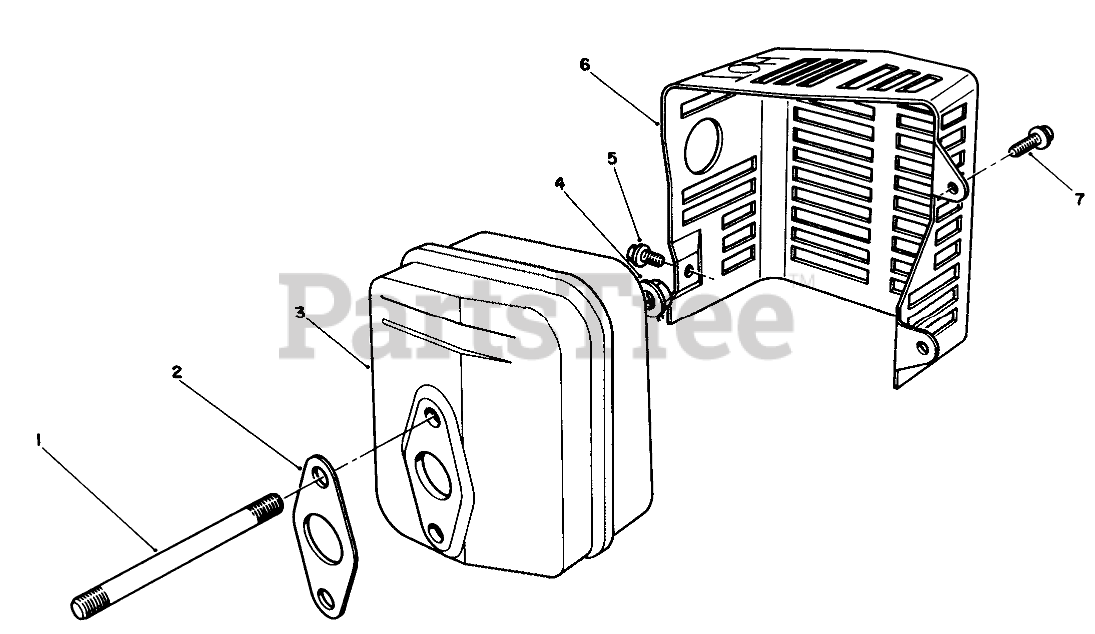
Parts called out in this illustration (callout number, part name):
2	GASKET
3	MUFFLER
5	SCREW
6	COVER
